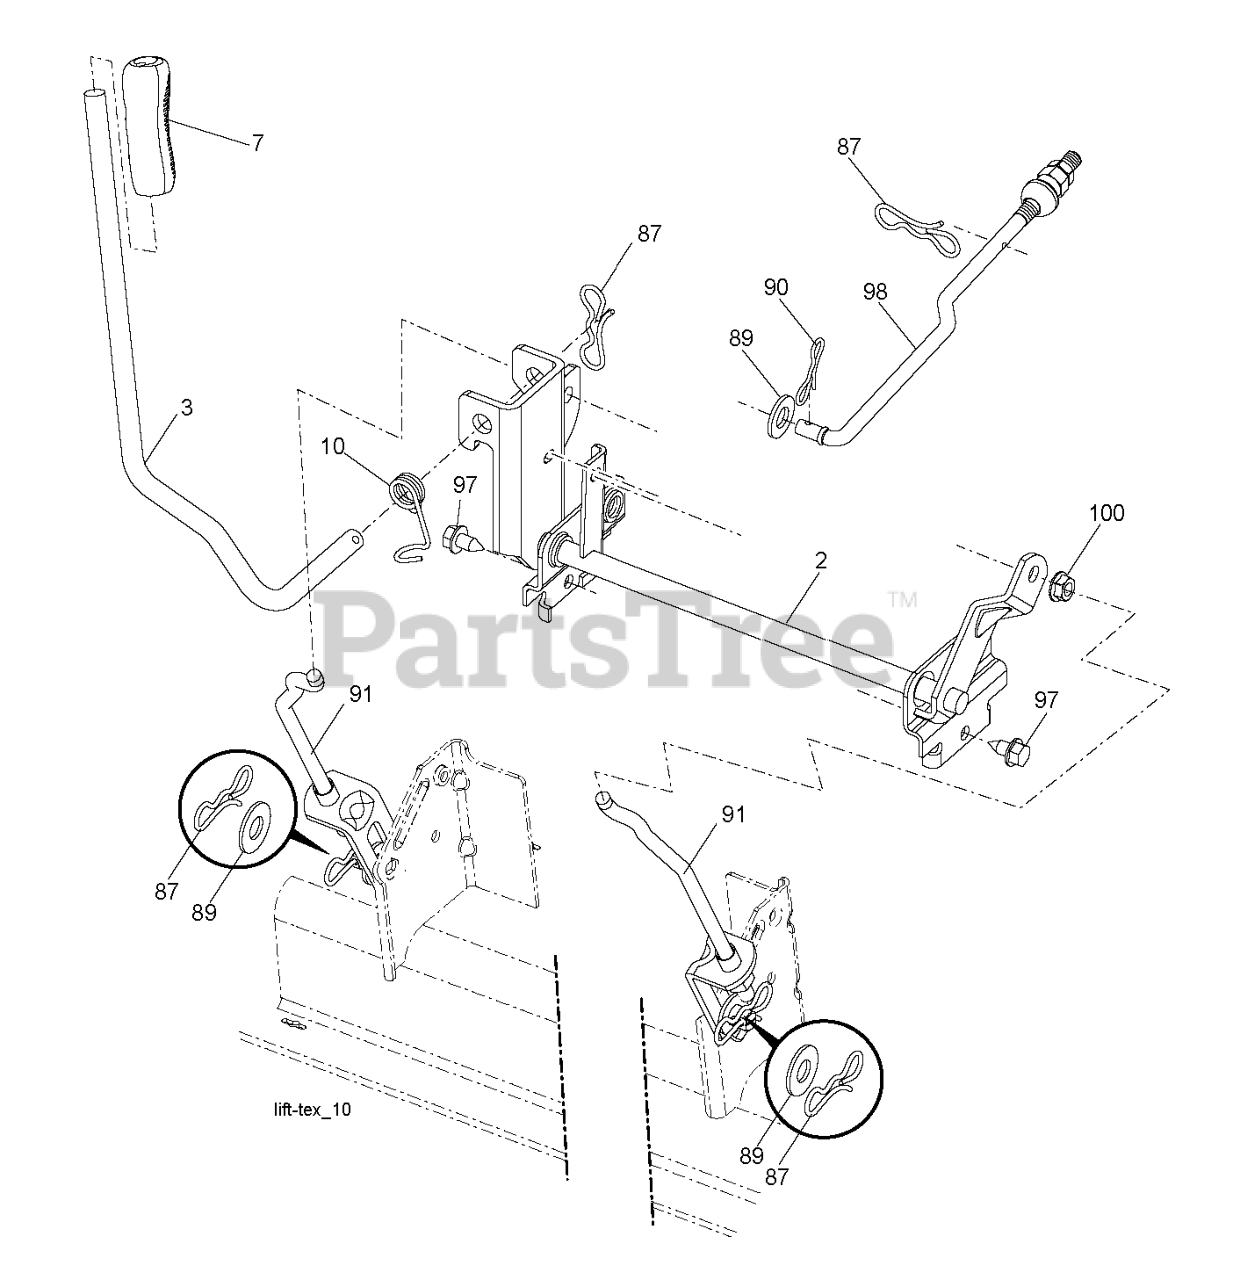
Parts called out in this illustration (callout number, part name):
2	SHAFT.ASM.LIFT.CROSS.H
3	LEVER.LIFT.HANDLE.LT
7	GRIP.HANDLE.LIFT.PVC.BLACK
10	SPRING.TORSION.LIFT.HANDLE
87	PIN.COTTER.7/16.BOW TI.
89	WASHER.CLEAR.ZINC
90	PIN.COTTER.5/16.BOW TI
91	LINK.ASM.LIFT.REAR
97	SCREW, 3/8-16X3/4
98	LINK.ASM.SUSP.FRONT.MW
100	LOCKNUT
